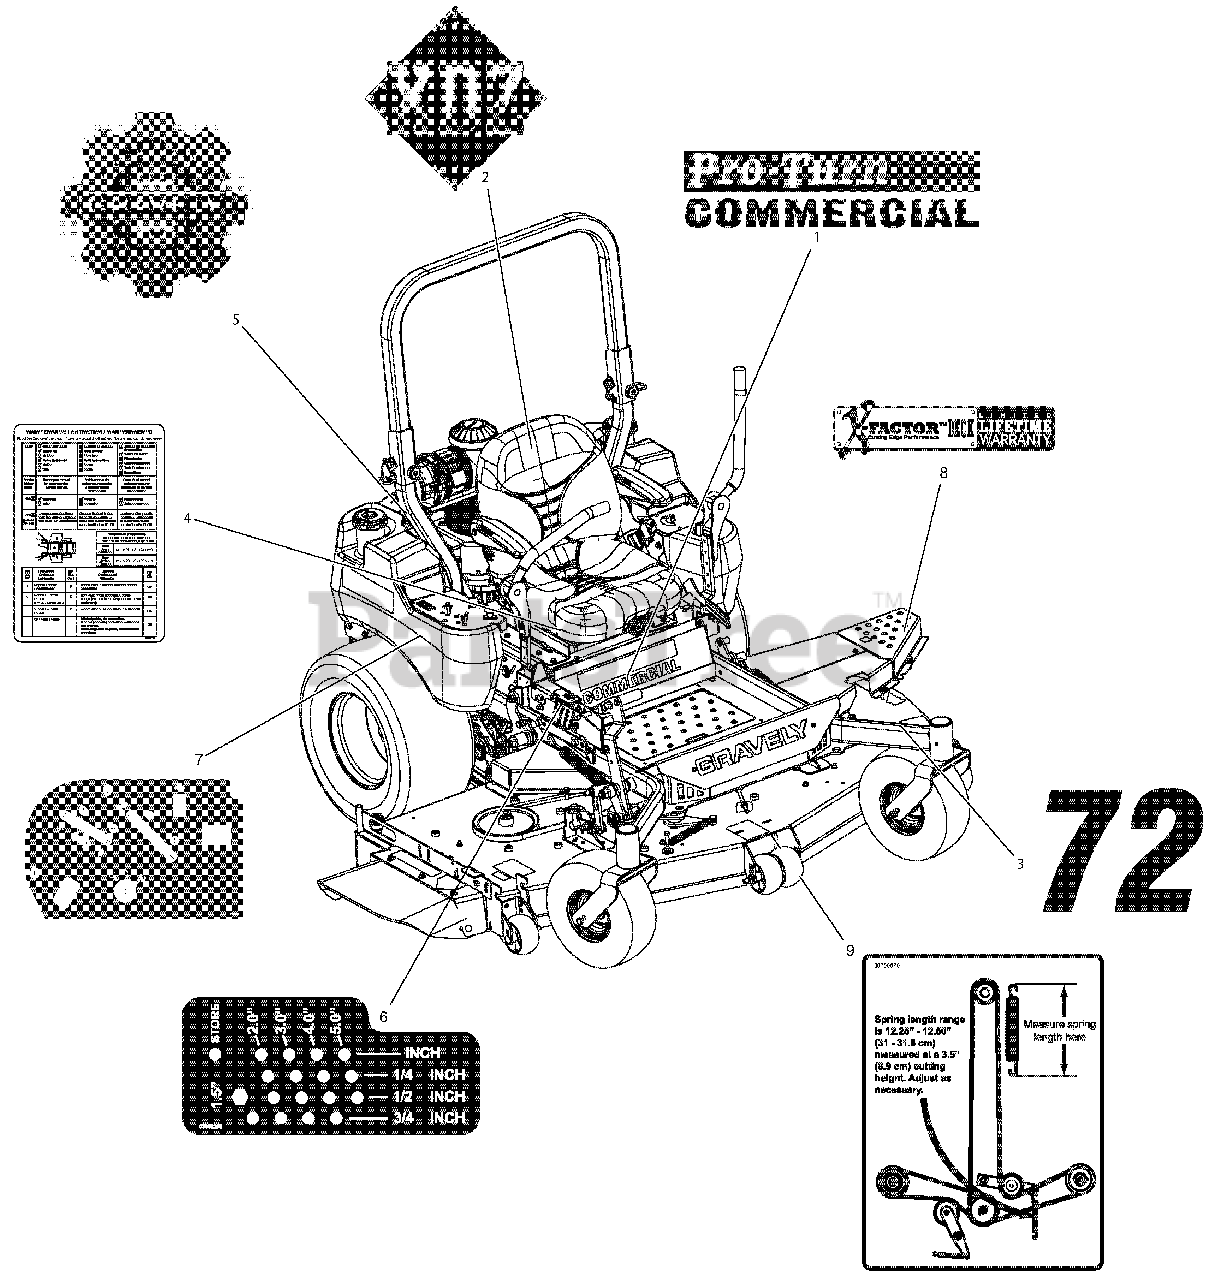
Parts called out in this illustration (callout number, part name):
1	DECAL, PRO-TURN 272
2	DECAL, XDZ
3	DECAL, 72"
4	DECAL, MAINTENANCE
5	DECAL, GRAVELY HERITAGE-LARGE
6	DECAL, HEIGHT OF CUT
7	DECAL, CONTROL PANEL NON-EFI
8	DECAL, X-FACTOR DECK
9	DECAL, BELT DIAGRAM 60"
